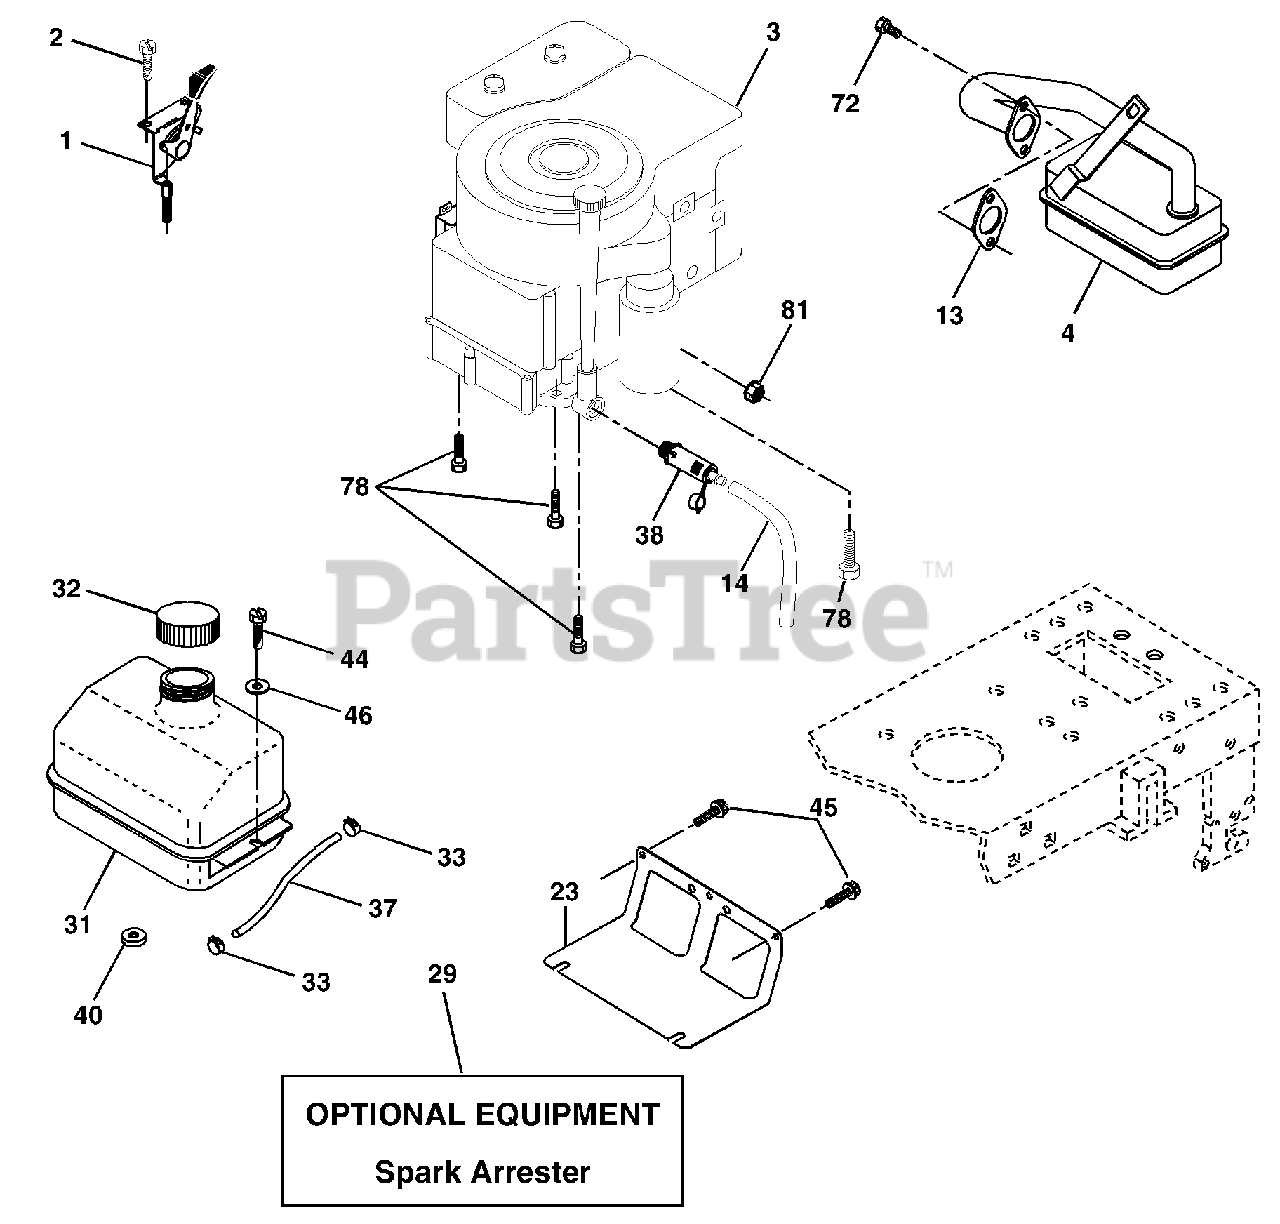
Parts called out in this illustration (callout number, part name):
1	Control Th/ch Flag
2	Screw Hex Thd Cut 1/4-20 x 1/2
13	Gasket Eng
14	Tube Drain Oil Easy
23	Shield Brn/Dbr Guard
29	Kit Spark Arrestor (Flat Scrn)
31	Tank Fuel Front
32	Cap Asm Fuel W/sym Vented
33	Clamp Hose Black
37	Line Fuel 20"
38	Plug Drain Oil Easy
40	Bushing Snap Nyl Blk Fuel Line
44	Screw Hexwsh Thdrol 1/4-20 x 3/4
45	Screw Hexwsh Thdr 3/8-16 x 3/4
46	Washer 9/32 x 7/8 x 16 Ga.
72	Screw Socket Head 5/16-18 x 1
78	Screw 3/8-16 x 1-1/4
81	Nut Keps Hex 1/4-20 unc
